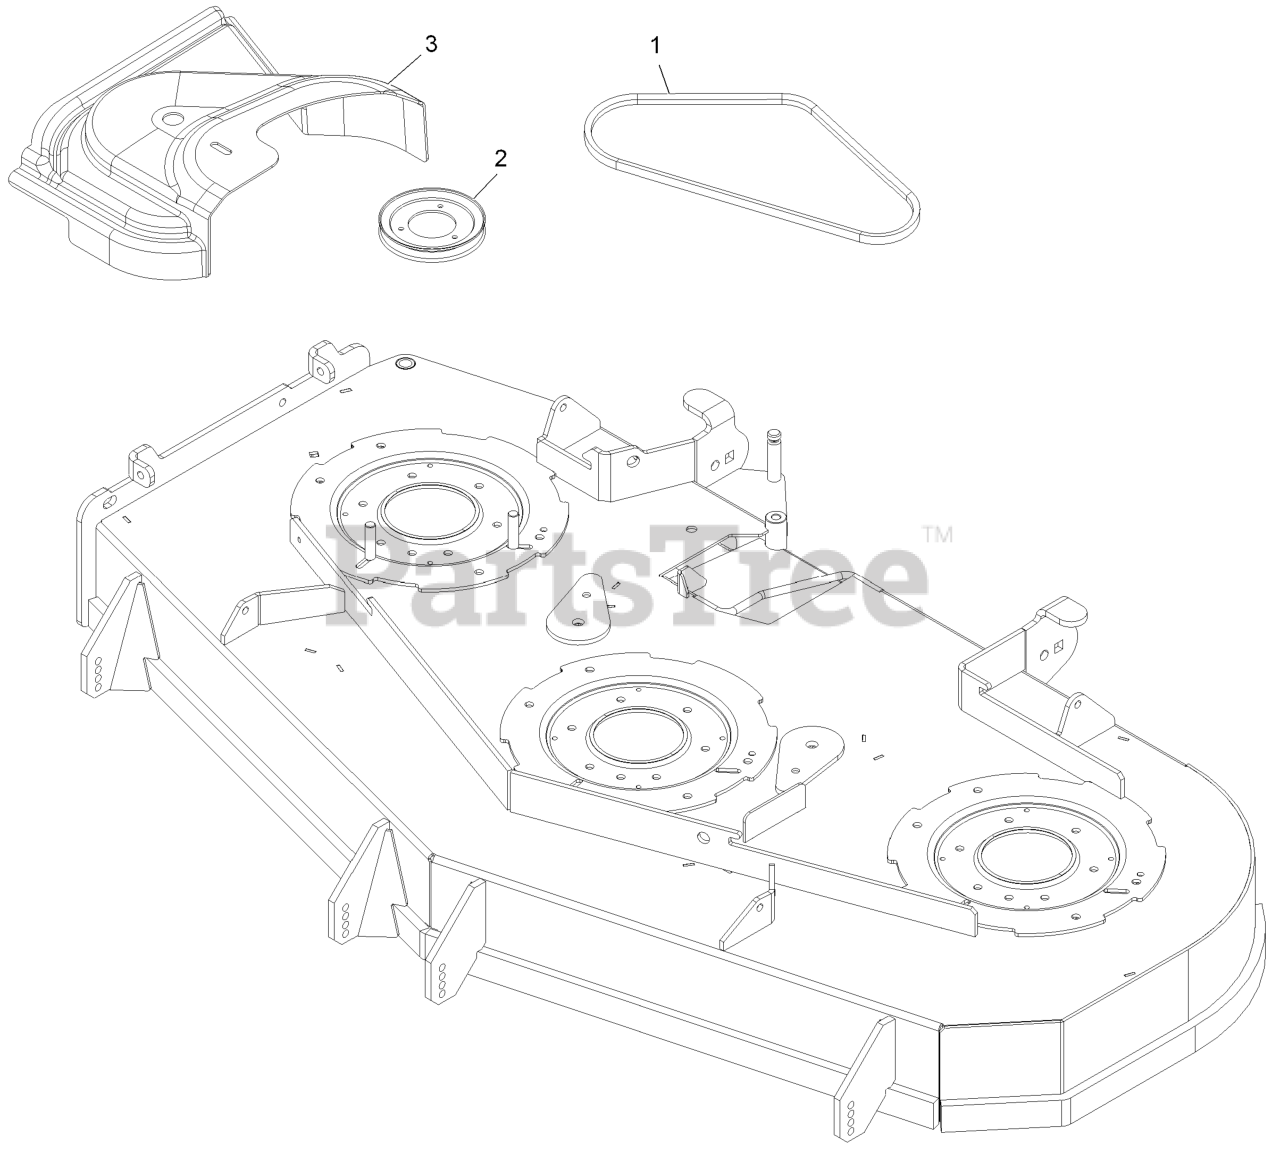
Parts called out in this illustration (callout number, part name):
1	Belt, Blower Drive 60
2	Sheave,Drive Lzuv 606
3	Cover,Belt Uv 60
